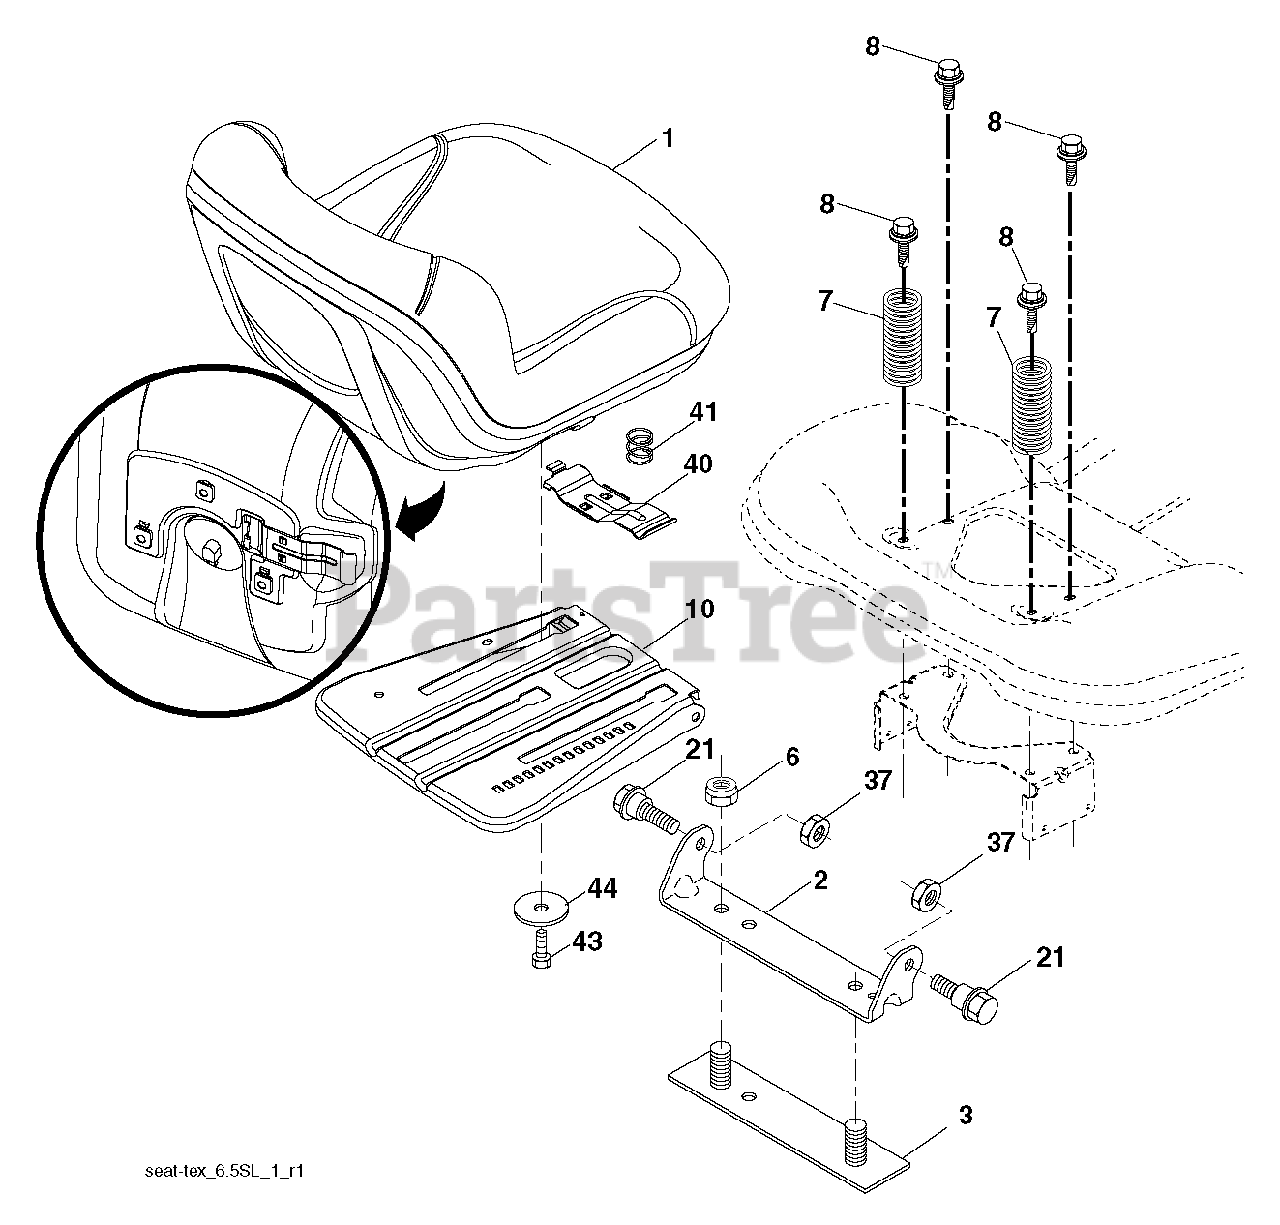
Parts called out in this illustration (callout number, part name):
1	SEAT.TG130.BLACK.NO/LOGO.
2	BRKT.PIVOT.FENDER
6	NUT
7	SPRING COMPRESSION
8	BOLT, 5/16-18 X 1 3/4
10	PAN.ASM.SEAT.3PT
21	BOLT.SHOULDER.5/16-18
37	NUT.71038.31-18.HEX.NYLOCK
40	HANDLE.SLIDE.SEAT.TEX.BLACK
41	SPRING.LATCH.SEAT.TEX
44	WASHER 13/32 X 2-3/8 X 12GA
